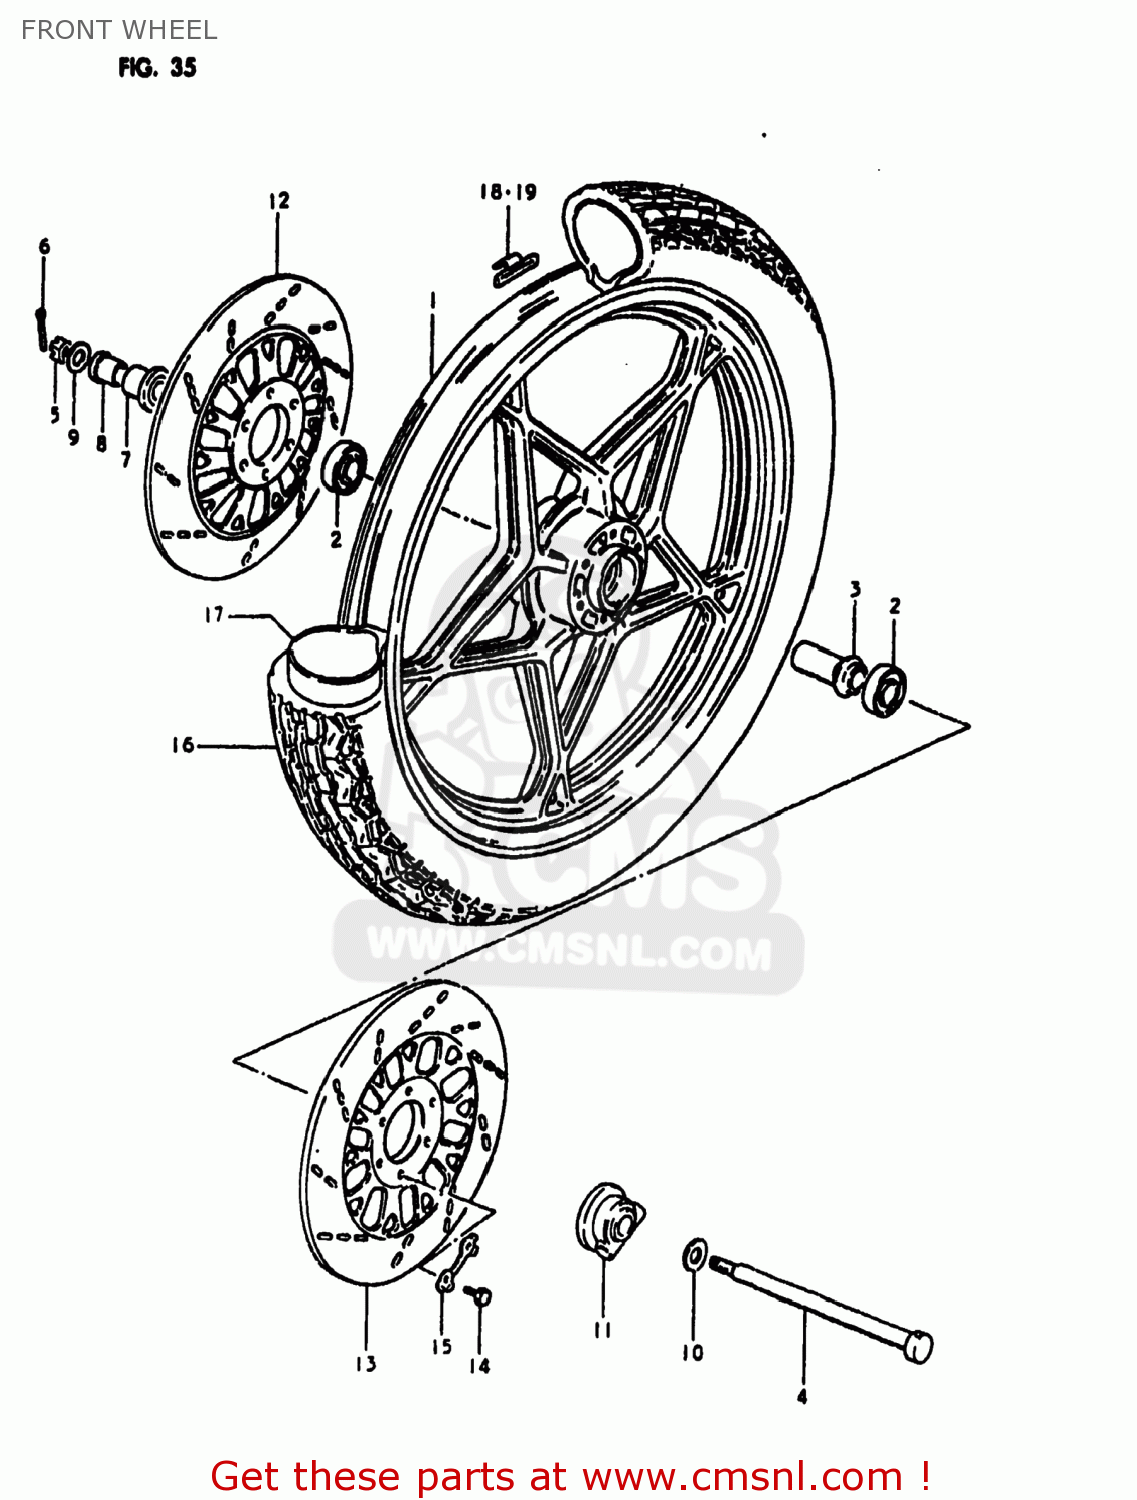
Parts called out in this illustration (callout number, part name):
1	WHEEL, FRONT
2	BEARING
3	SPACER,FR HUB BEARING
4	AXLE,FR
5	NUT 12MM
6	COTTER PIN
7	SPACER,FR AXLE,R
8	SPACER
9	WASHER
10	WASHER(15.5X26X2.3)
11	BOX ASSY,SPEEDOMETER GEAR
12	DISC,FR BRAKE,R
13	DISC,FR BRAKE,L
14	BOLT(8X25)
15	WASHER
16	TIRE,FRONT
17	TUBE,INNER
18	BALANCER,WHEEL
19	BALANCER,WHEEL
